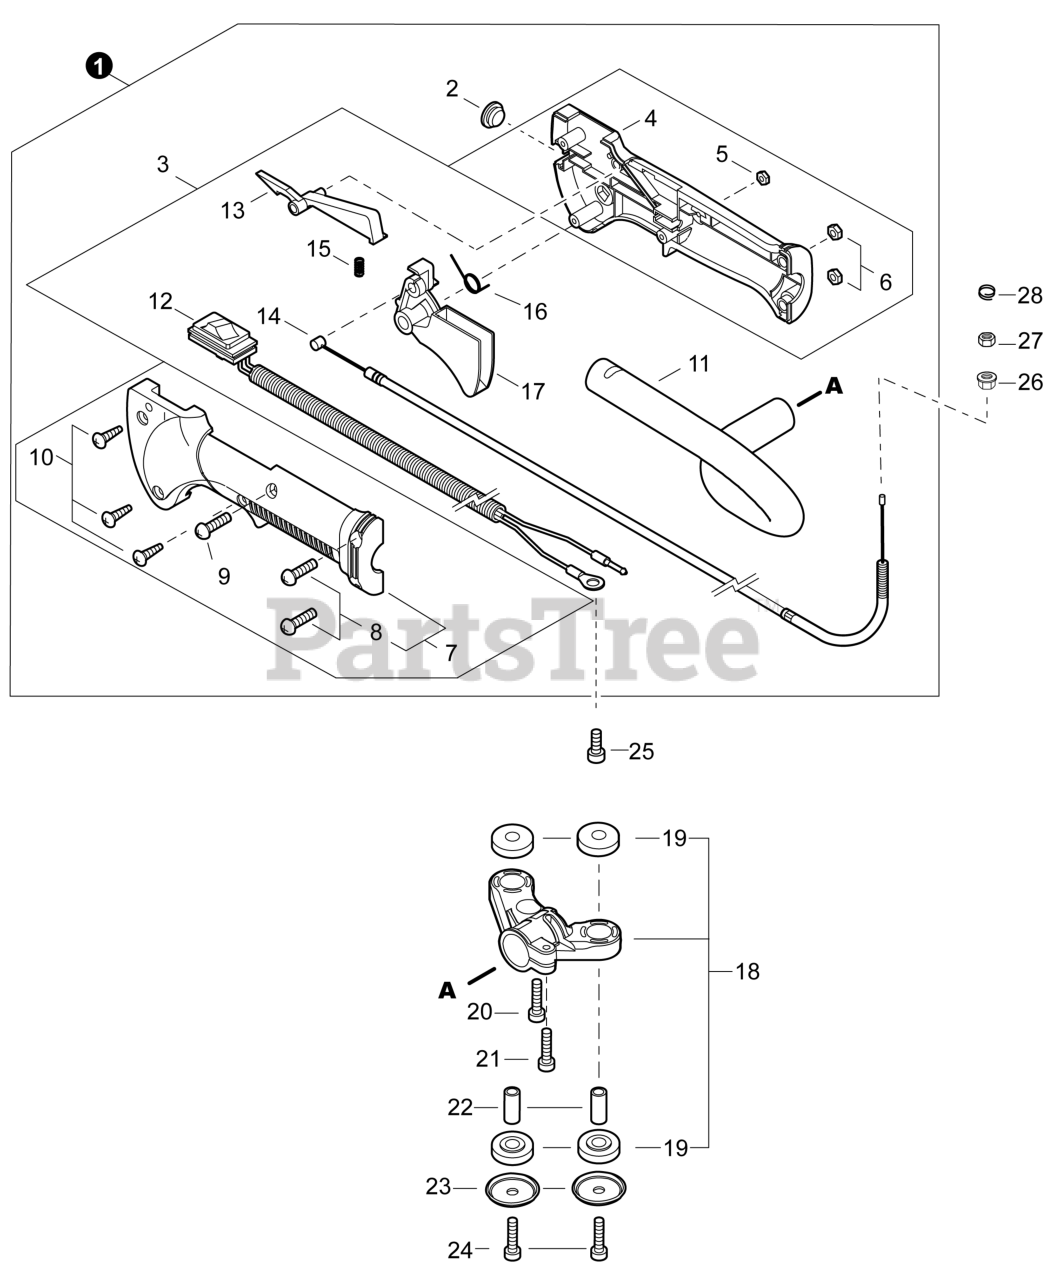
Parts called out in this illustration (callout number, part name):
1	HANDLE ASSY, REAR
2	PLUG, RUBBER
3	HANDLE KIT
4	CONTROL HANDLE - RIGHT
6	NUT, LOCK M5
7	CONTROL HANDLE KIT
8	SCREW M5x22
9	SCREW M4x23
10	SCREW, TAPPING 4x16
11	HANDLE, REAR
12	SWITCH ASSY, ON-OFF
13	LOCKOUT, THROTTLE
14	CABLE, THROTTLE
15	SPRING, COMPRESSION
16	SPRING, TORSION
17	TRIGGER, THROTTLE
18	SUPPORT ASSY, HANDLE
19	CUSHION
20	BOLT, TORX 5x12
21	BOLT, TORX 5x16
22	COLLAR 6
23	WASHER 6
24	BOLT, TORX 6
25	BOLT, TORX 4x10
26	NUT, FLANGE M6
